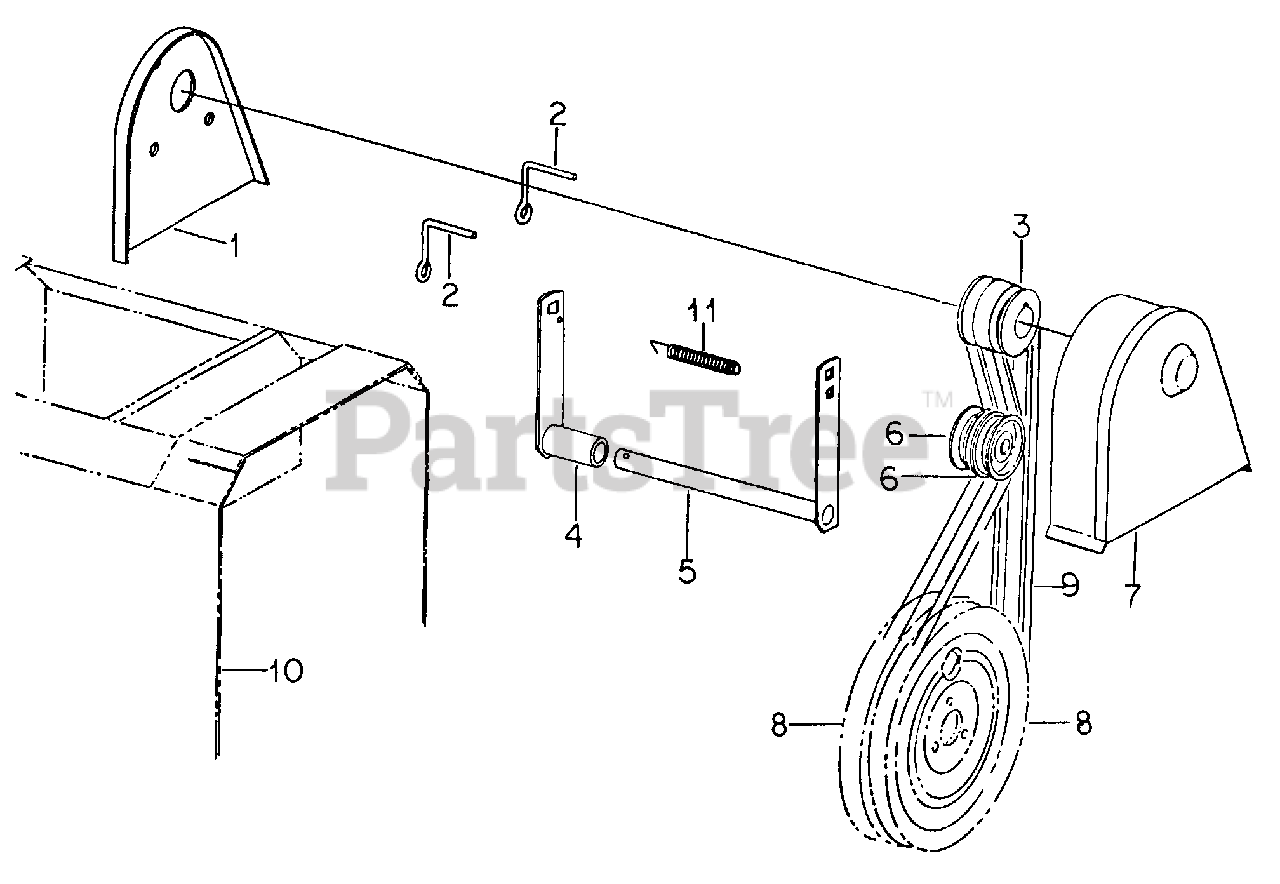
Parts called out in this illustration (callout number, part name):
1	PLATE, BELT GUARD BACK
2	GUIDE, BELT
3	SHEAVE, ENGINE DRIVEN
4	ARM, IDLER - SHORT
5	ARM, IDLER - LONG
6	PULLEY, IDLER
7	PLATE, BELT GUARD FRONT
8	SHEAVE
10	HOUSING, WELDED
